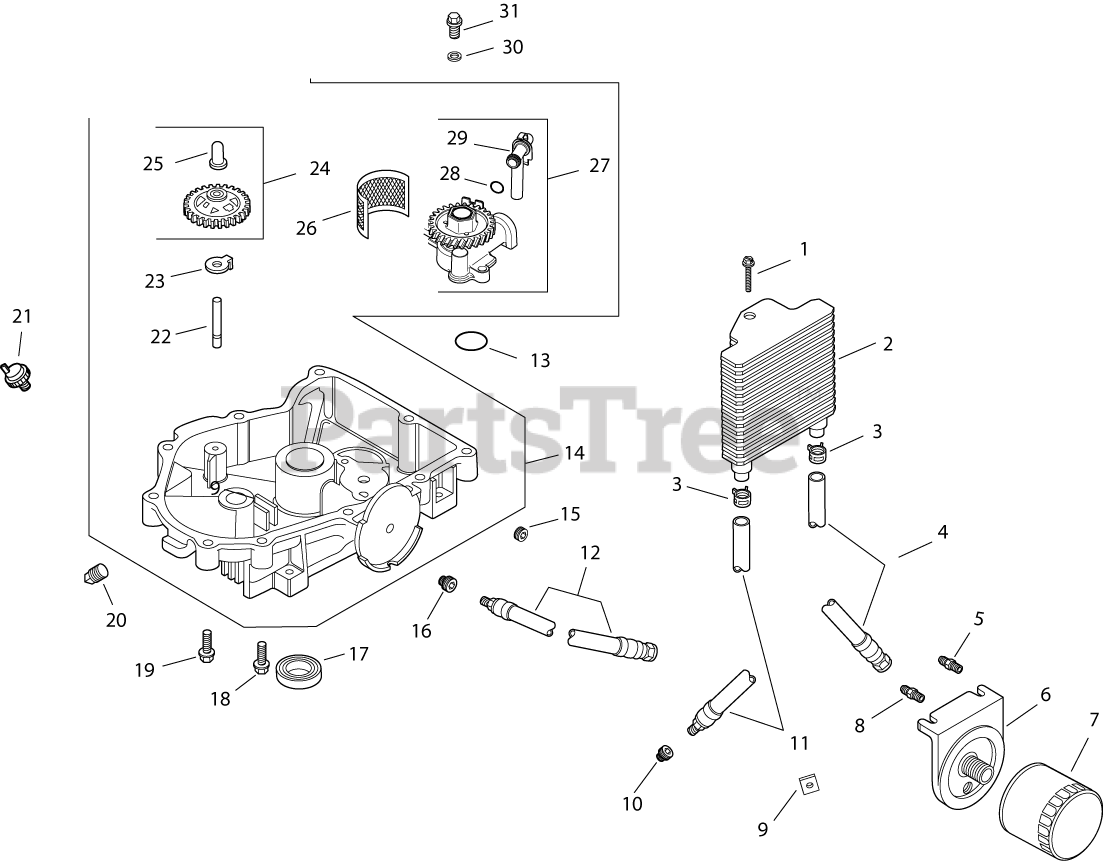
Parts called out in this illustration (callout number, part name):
1	SCREW, TAP M6X1.7X18
2	COOLER, OIL
3	CLAMP, OIL COOLER HOSE-USE 25 237 31-S
4	HOSE, OIL
7	OIL FILTER
8	CONNECTOR
9	NUT, PLASTIC (KM)-USE 25 100 37-S
10	BUSHING, REDUCING
11	HOSE, OIL
14	OIL PAN ASSEMBLY - USE 24 199 32-S
15	PLUG, PIPE CTSK 3/8"
16	BUSHING, REDUCING
17	SEAL, OIL (KM)-USE 25 032 06-S
18	SCREW, FLG M8X1.25X45
19	SCREW, HEX FLANGE -USE 24 086 17-S
20	PLUG, SQ HD PIPE 3/8"
21	SENSOR, OIL PSI
22	SHAFT, GOVERNOR GEAR
23	TAB, LOCKING
24	KIT, GOVERNOR GEAR W/PIN
25	PIN, GOVERNOR REGULATING
26	SCREEN, OIL
27	PUMP ASSEMBLY, OIL-USE 24 393 53-S
28	O-RING, OIL PICK-UP
29	KIT, OIL PICK-UP TUBE
30	SCREW,FLG THD FRM M6X1.0X25-(#25086395S)
31	WASHER, FLAT 6 MM
